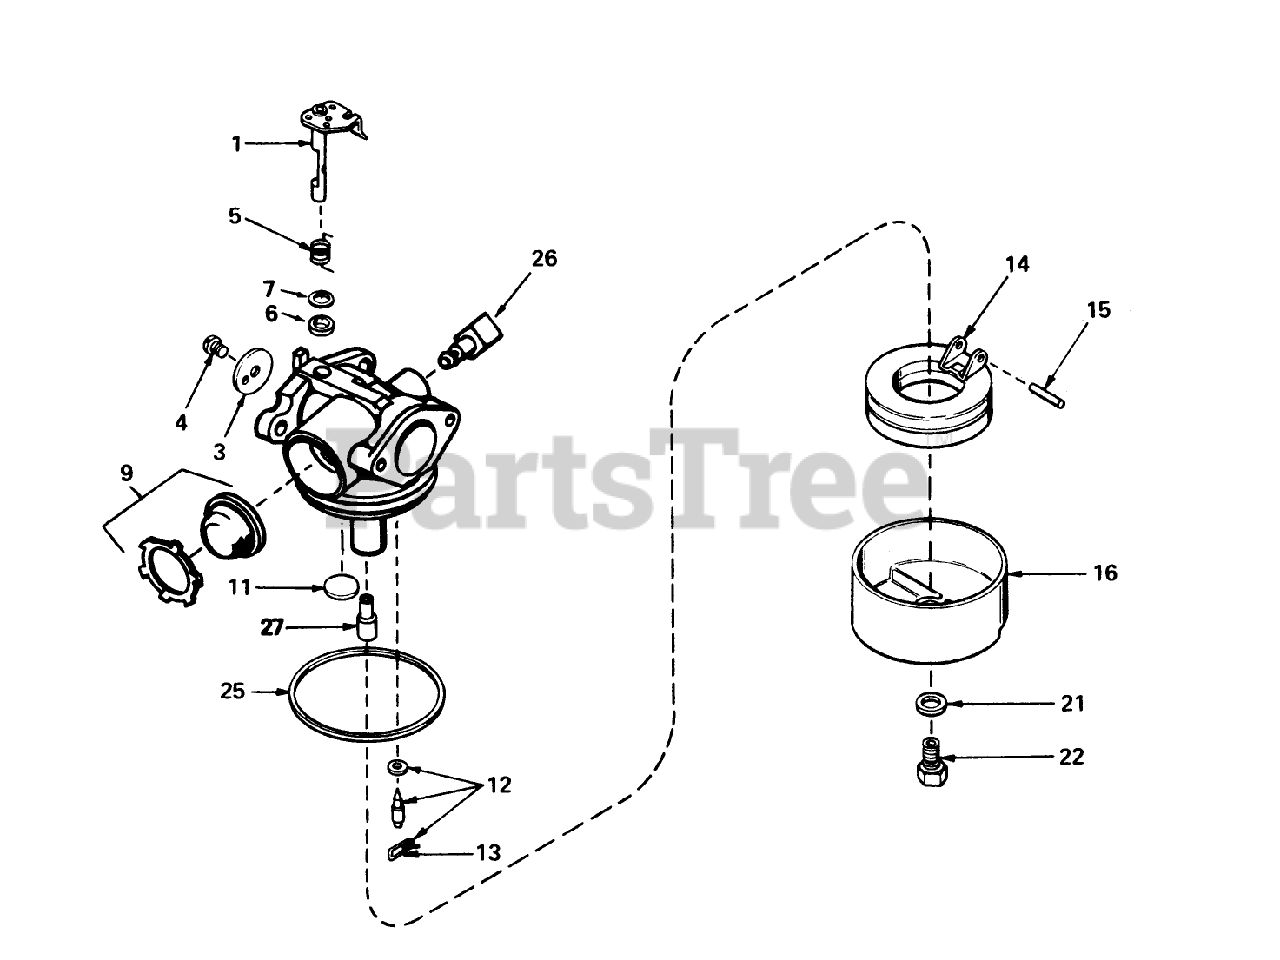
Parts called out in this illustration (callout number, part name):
1	Throttle Shaft and Lever ASM
3	Throttle-Shutter
4	Screw-Shutter
5	Spring-Return, Throttle
6	Seal-Dust
7	Washer-Seal, Dust
9	Primer Assy.
11	Plug-Welch, Atmospheric Vent
12	Inlet Needle, Seat Clip Assy. (Incl. No. 13)
13	Clip-Spring
14	Float
15	Shaft-Float
16	Bowl Float
21	Gasket-Bowl
22	Nut-Float Bowl
25	O Ring-Bowl, Float
26	Fitting-Fuel
27	Spacer
